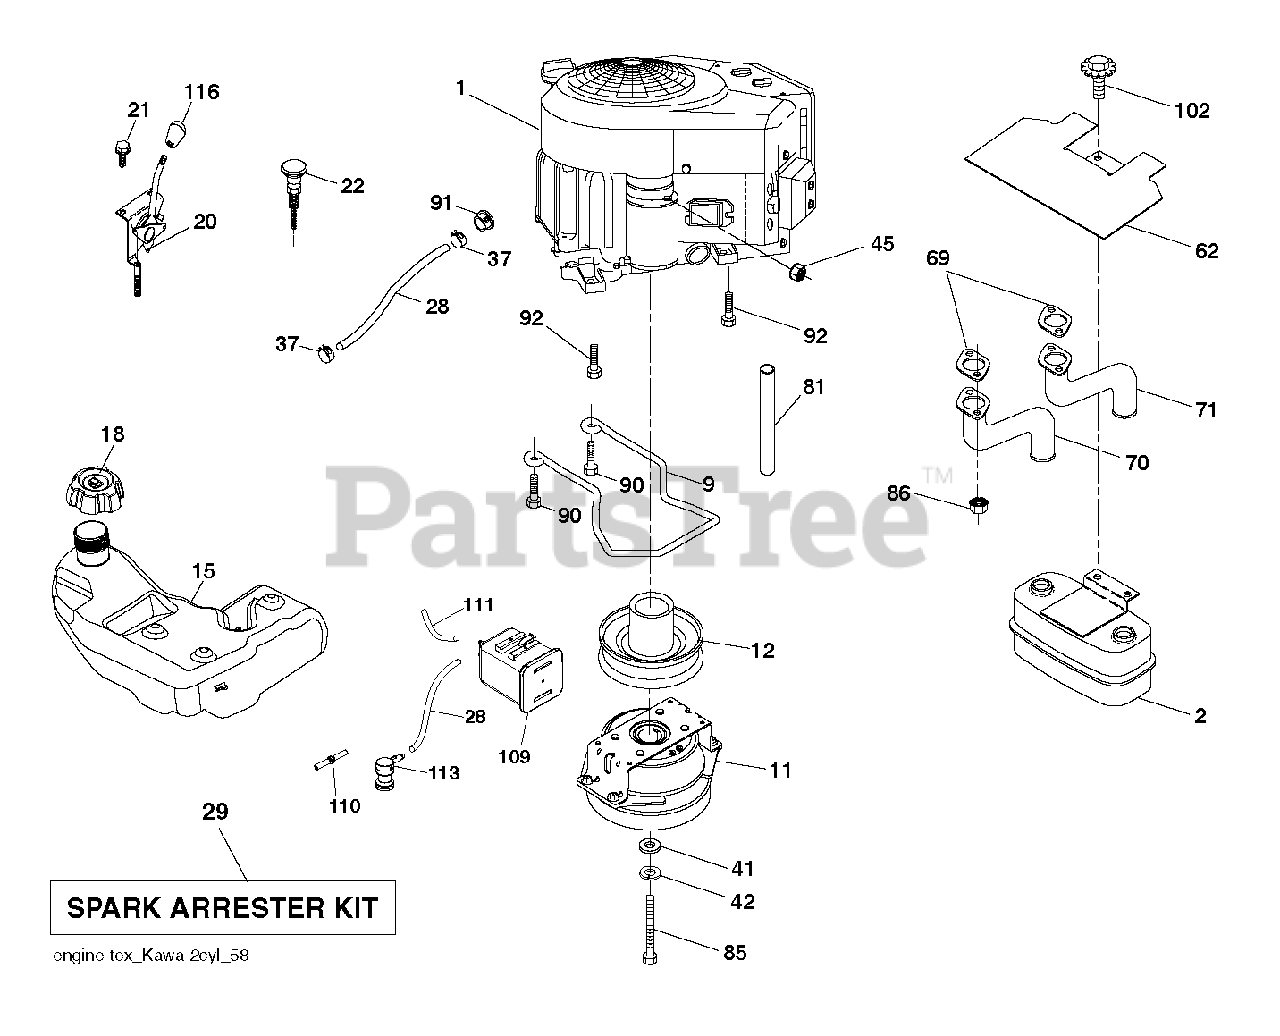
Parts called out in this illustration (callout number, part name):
2	MUFFLER.ASM.TWN.EXTNDED.DFLCTR
9	KEEPER.BELT.ENG.4.25"2.BLT.431
11	CLUTCH.OGURA.4.4PD.GT1.5-EH13V
12	PULLEY.ENGINE.TUFFTORQ
15	Fuel Assembly Tank, 3 Gallon
18	CAP ASSY FUEL 3" GRAY
20	CONTROL.THROTTLE.PRO.
21	SCREW.#10 X 0.750.BOS
22	CONTROL.CHOKE.ERGO.PUSH-IN.BLA
28	LINE.FUEL.64"REAR.EMIS
29	KIT.SPARK ARRESTOR 794945 B&S
37	HOSE CLAMP
42	WASHER 7/16 LOCK
45	NUT
62	SHIELD.HEAT.MUFFLER
70	TUBE.EXHAUST.RH.FR961/FR730
71	TUBE.EXHAUST.LH.FR961/FR730
81	TUBE, DRAIN OIL ASM.
85	CLUTCH BOLT7/16-20X3.5 GR524HR
86	NUT.HEX.FLANGE.TOPLOCK
90	SCREW 3/8-16X1
91	BUSHING.1.375OD
92	SCREW 3/8-16X1
102	SCREW
109	CANNISTER, CARBON
110	VALVE.ASM.ANTI-SLOSH
111	RP PURGE LINE
113	VALVE.SLANT.CARTRDG.90 DEG.TEX
116	KNOB - SHIFT
